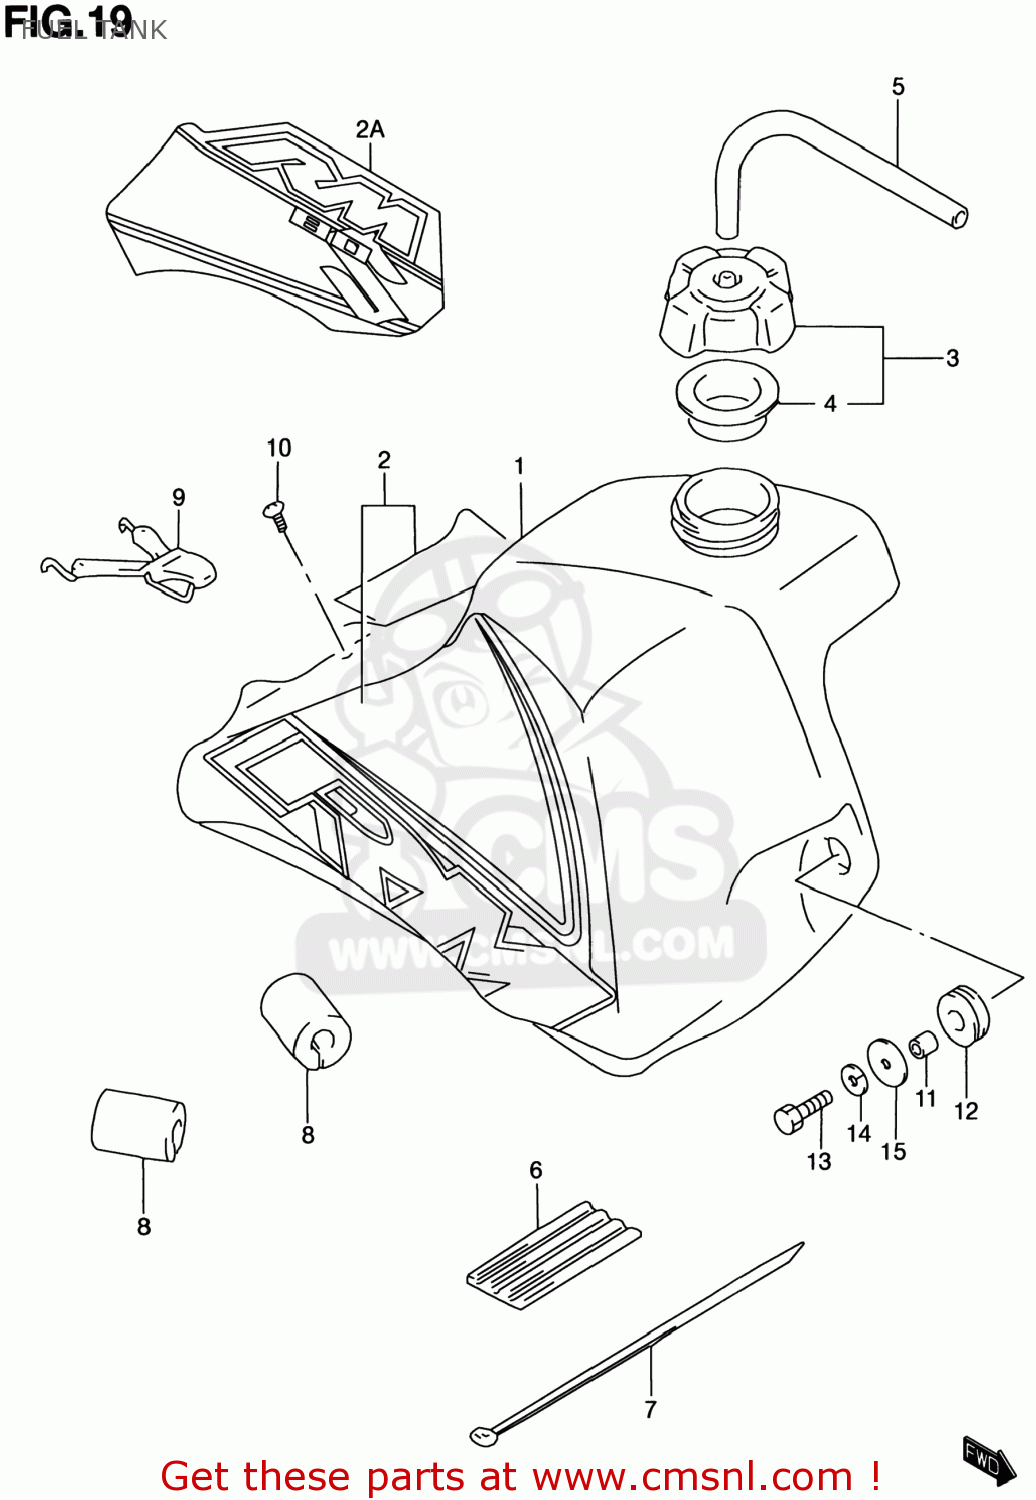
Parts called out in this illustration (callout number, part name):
1	TANK,FUEL(YELLOW)
2	TAPE SET,FUEL TANK
2A	TAPE SET,FUEL TANK
3	CAP SET,FUEL TANK
4	GASKET,CAP (NAS)
5	HOSE(5X8.2X600)
6	CUSHION,FUEL TANK UPR FR
7	CLAMP(L:250)
8	CUSHION,FUEL TANK UPR RR
9	BAND,FUEL TANK RR
10	SCREW
11	SPACER(6.5X10X11.5)
12	CUSHION
13	BOLT
14	LOCK WASHER
15	WASHER(6.5X24X1.6)
